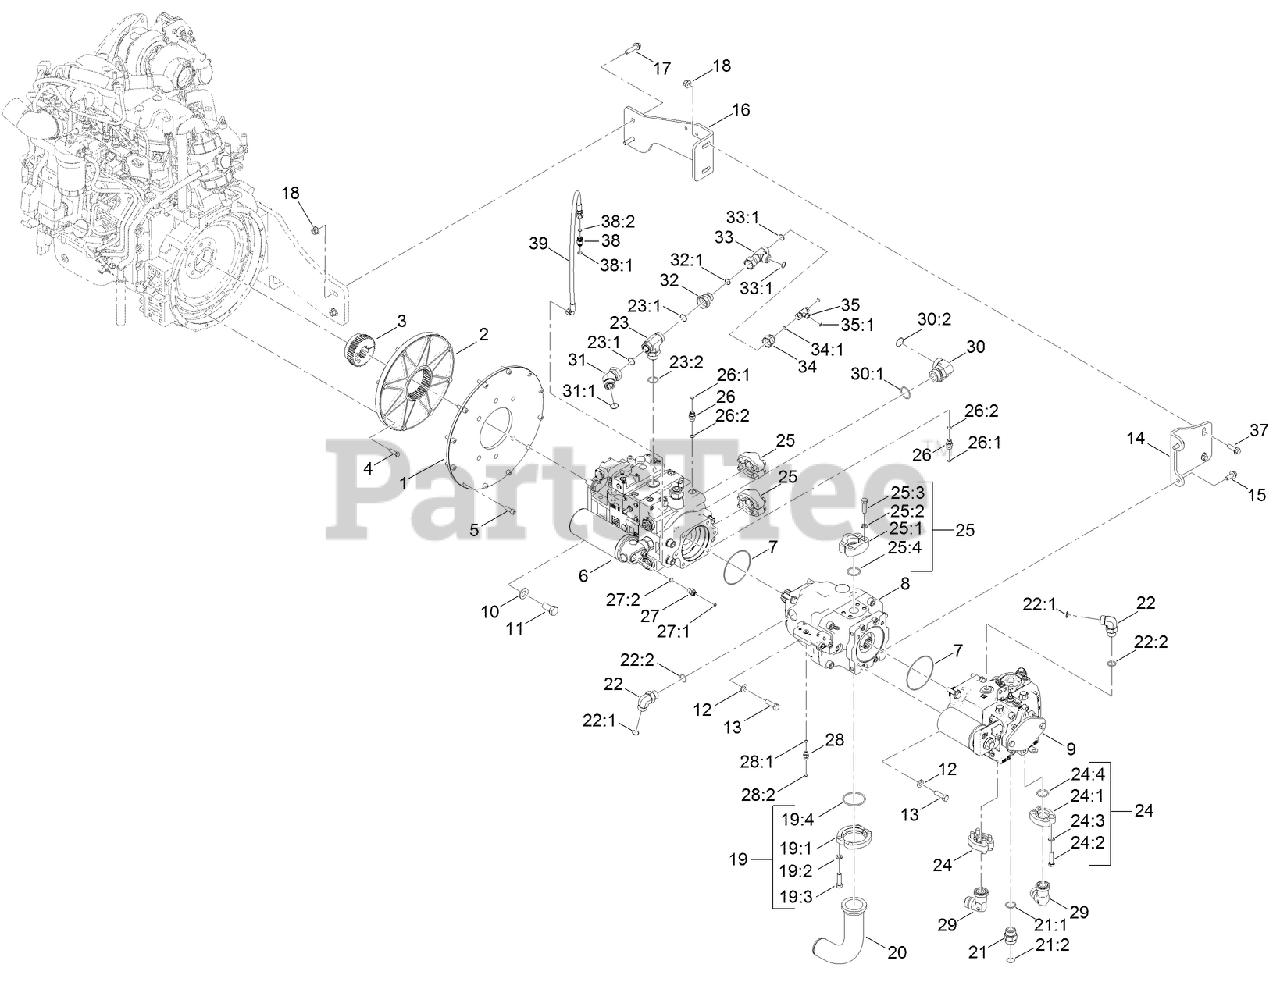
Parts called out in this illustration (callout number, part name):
1	PLATE-MOUNT, PUMP
2	COUPLING-DRIVE, NYLON
3	HUB-STEEL, 13T
4	SCREW-HH
5	SCREW-HSH
6	ROTARY PUMP ASM
7	SEAL-O RING
8	LOAD-SENSE PUMP ASM
9	HYDROSTAT PUMP ASM
12	WASHER-FLAT
13	SCREW-HH
14	BRACKET-MOUNTING, PUMP
15	SCREW-HHF
16	BRACKET-MOUNTING, CENTER
17	SCREW-HHF
18	NUT-LOCK, HHF
19	SPLIT FLANGE KIT
19:1	Deck ASM
19:2	SCREW-HH
19:3	SCREW-HH
19:4	O-RING
20	TUBE-BENT
21	FITTING-STRAIGHT
21:1	O-RING
21:2	O-RING
22	FITTING-ELBOW-90
22:1	O-RING
22:2	O-RING
23	FITTING-HYD
23:1	O-RING
23:2	O-RING
24	FLANGE KIT
24:1	O-RING
24:2	SCREW-HH
24:3	WASHER-LOCK
24:4	Deck ASM
25	SPLIT FLANGE KIT
25:1	FLANGE-HALF
25:2	SCREW-HH
25:3	SCREW-HH
25:4	O-RING
26	FITTING-STRAIGHT
26:1	O-RING
26:2	O-RING
27	FITTING-STRAIGHT
27:1	O-RING
27:2	O-RING
28	FITTING-STRAIGHT
28:1	O-RING
28:2	O-RING
29	ELBOW-90
30	FITTING-ELBOW 90
30:1	O-RING
30:2	O-RING
31	FITTING-ELBOW, 45
31:1	O-RING
32	FITTING-REDUCER
32:1	O-RING
33	FITTING-TEE
33:1	O-RING
34	FITTING-REDUCER
34:1	O-RING
35	FITTING-TEE, SWIVEL NUT
35:1	O-RING
37	SCREW-HHF
38	CHECK VALVE
38:1	O-RING
38:2	O-RING
39	HOSE ASM-HYD
